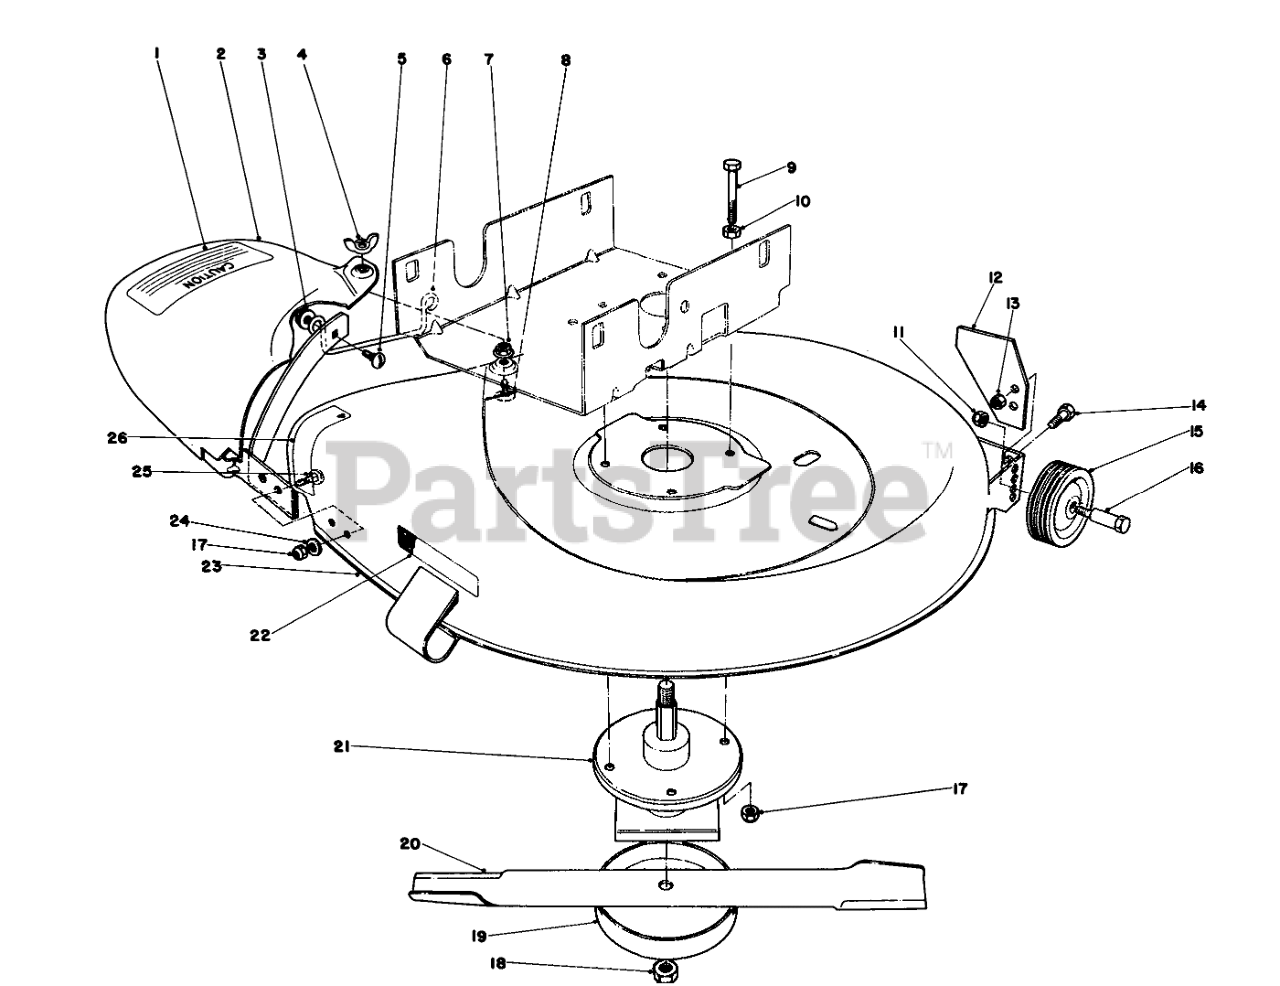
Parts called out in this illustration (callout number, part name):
3	NUT-LOCK, HHF
9	SCREW-HH
10	NUT-JAM
13	NUT-LOCK, CONE
14	SCREW-HH
17	NUT-LOCK, CONE
18	NUT-SPECIAL
22	Decal-Deck Inst.
24	WASHER-FLAT
25	BOLT-CARR
